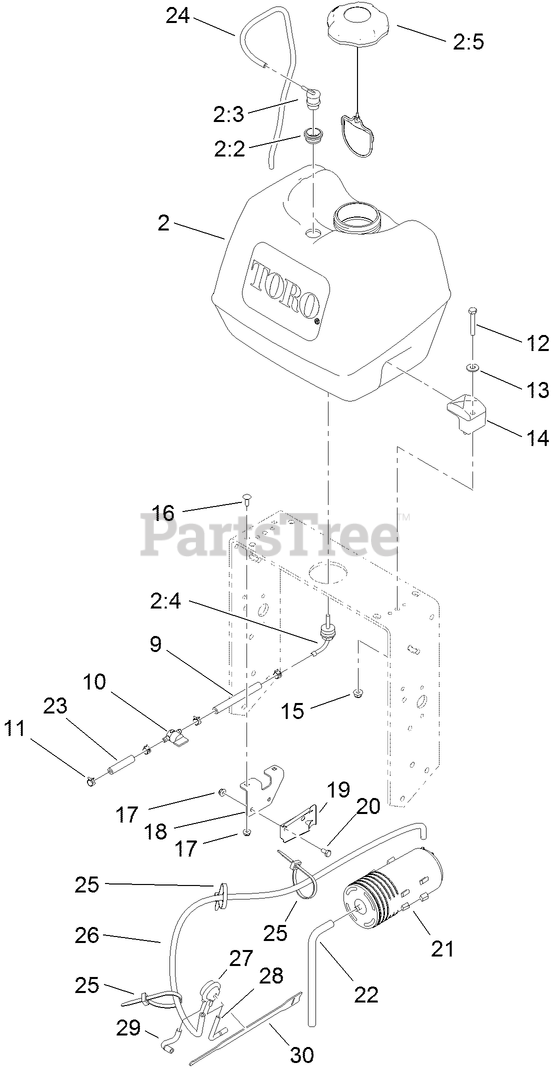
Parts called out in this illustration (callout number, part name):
2	FUEL TANK ASM
2:2	GROMMET
2:3	VALVE-VENT, FUEL
2:4	FITTING-FUEL, BULKHEAD
2:5	CAP-FUEL, RATCHETING
9	HOSE-FUEL
10	VALVE-FUEL
11	CLAMP-HOSE
12	SCREW-HH
13	WASHER-FLAT
15	NUT-HF, NI
16	BOLT-CARR
17	NUT-HF
18	BRACKET-CANISTER, CARBON
19	BRACKET-CANISTER, CARBON
20	SCREW-HH
21	CANISTER-CARBON, 800CC
22	HOSE-VENT, CANISTER
23	HOSE-FUEL
24	HOSE-VENT
25	TIE-CABLE
26	HOSE-VENT, FORMED
27	VALVE-CONTROL, VACUUM
28	HOSE-VENT, FORMED
29	HOSE-VENT, FORMED
30	STRAP-VELCRO, CABLE TIE
